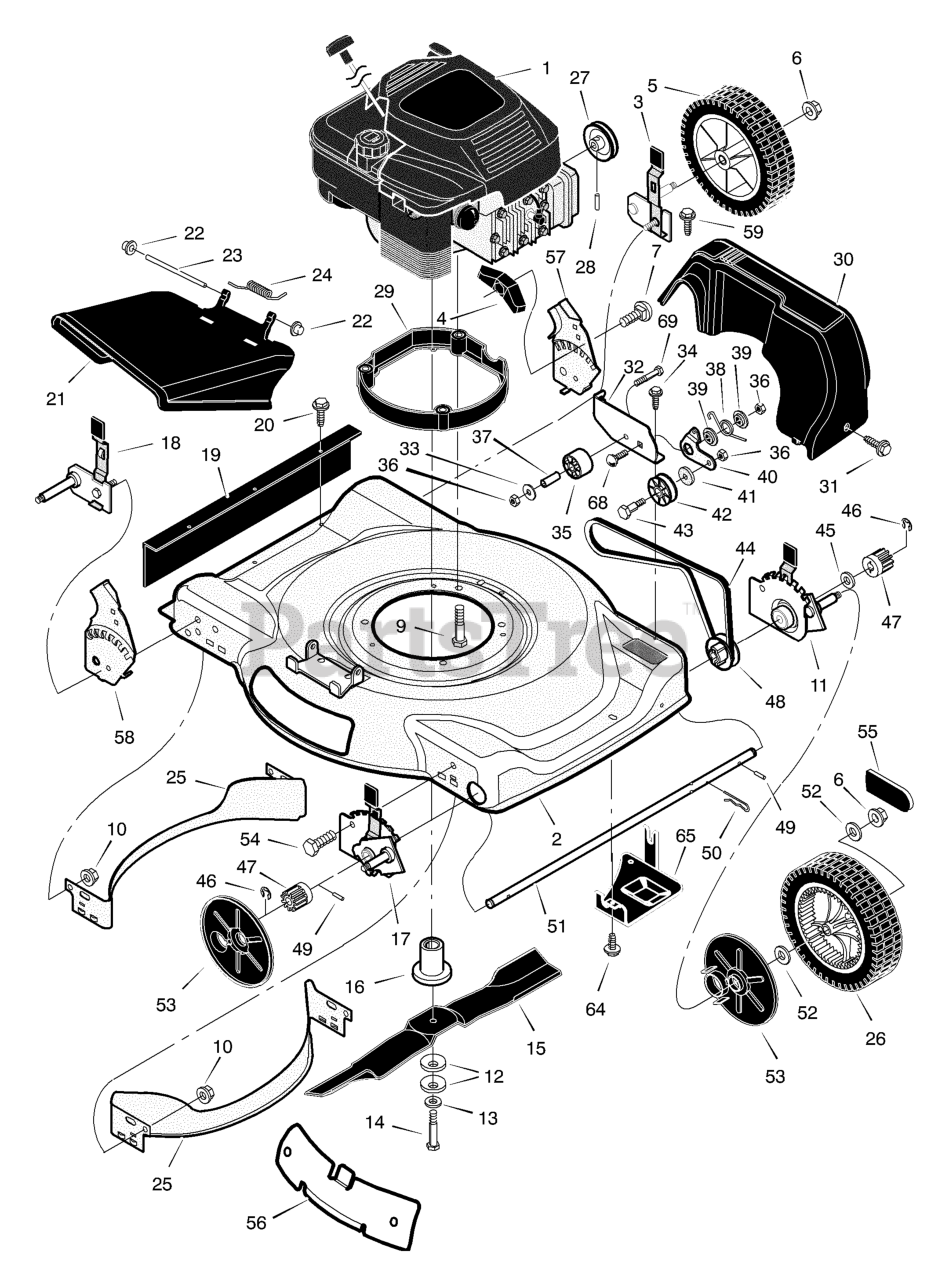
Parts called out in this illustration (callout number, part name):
1	Engine
2	Housing
3	Height Adjuster, Left Rear
5	Wheel and Tire, Rear
6	Locknut, Flange
7	Bolt, Carriage
9	Bolt, Engine
10	Nut
11	Height Adjuster, Left Front
12	Washer, Belleville
14	Bolt, Hex
15	Blade, 3-n-1
16	Adapter, Blade
17	Height, Adjuster, Right Frt.
18	Height, Adjuster, Right Rr.
19	Guard, Rear
20	Screw
21	Deflector, Chute
22	Push-On Cap
23	Pin, Pivot
24	Spring
25	Baffle
26	Wheel and Tire, Drive
28	Pin, Spring
29	Base, Engine
30	Cover, Belt (Black)
32	Bracket, Idler Support
33	Washer
34	Screw
35	Idler, Backside
36	Locknut
37	Bearing
40	Arm, Pivot
42	Pulley, Idler
43	Bolt, Shoulder
46	Ring, Retainer
47	Gear, Pinion
49	Pin, Drive
50	Pin, Hair
52	Washer
53	Cover, Dust
54	Bolt
55	Hub Cap
56	Plate, Mulch
57	Bracket, Left Handle
58	Bracket, Right Handle
65	Shield, Debris
68	Bolt, Carriage
